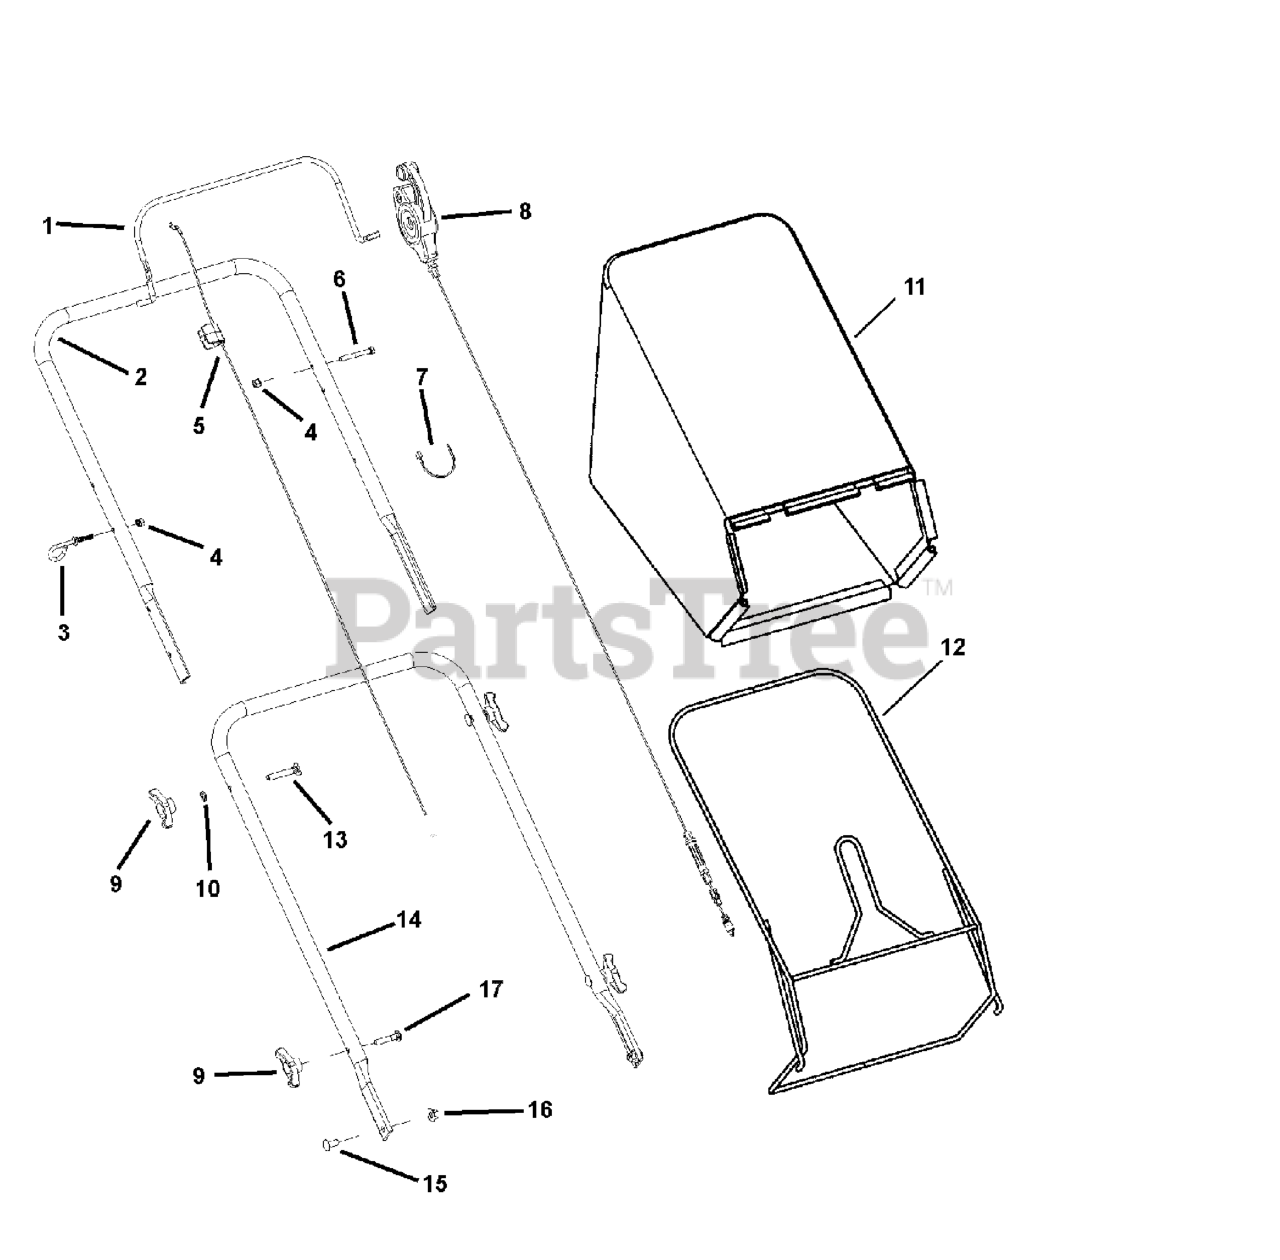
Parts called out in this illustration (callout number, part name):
1	BAIL, OPC Propelled
2	HANDLE, Upper
3	GUIDE, Rope, 1/4-20 thread
4	NUT, Nylock, 1/4-20
5	CABLE, Bail, Std Propelled, 53.5"
6	CAPSCREW, Hex Head, 1/4-20 x 2-1/4, GR 5
7	WIRE TIE
8	CONTROL, Drive, Single Speed Std Wheel
9	KNOB, Wing, 5/16-18
10	WASHER, Internal Tooth Lock, 5/16
11	BAG, Cloth, Grass Bag
12	FRAME, Grass Bag
13	BOLT, Carriage, 5/16-18 x 2, GR2
14	HANDLE, Lower
15	BOLT, Carriage, 5/16-18 x 5/8
16	NUT, Hex, 5/16-18
17	BOLT, Carriage, 5/16-18 x 1
